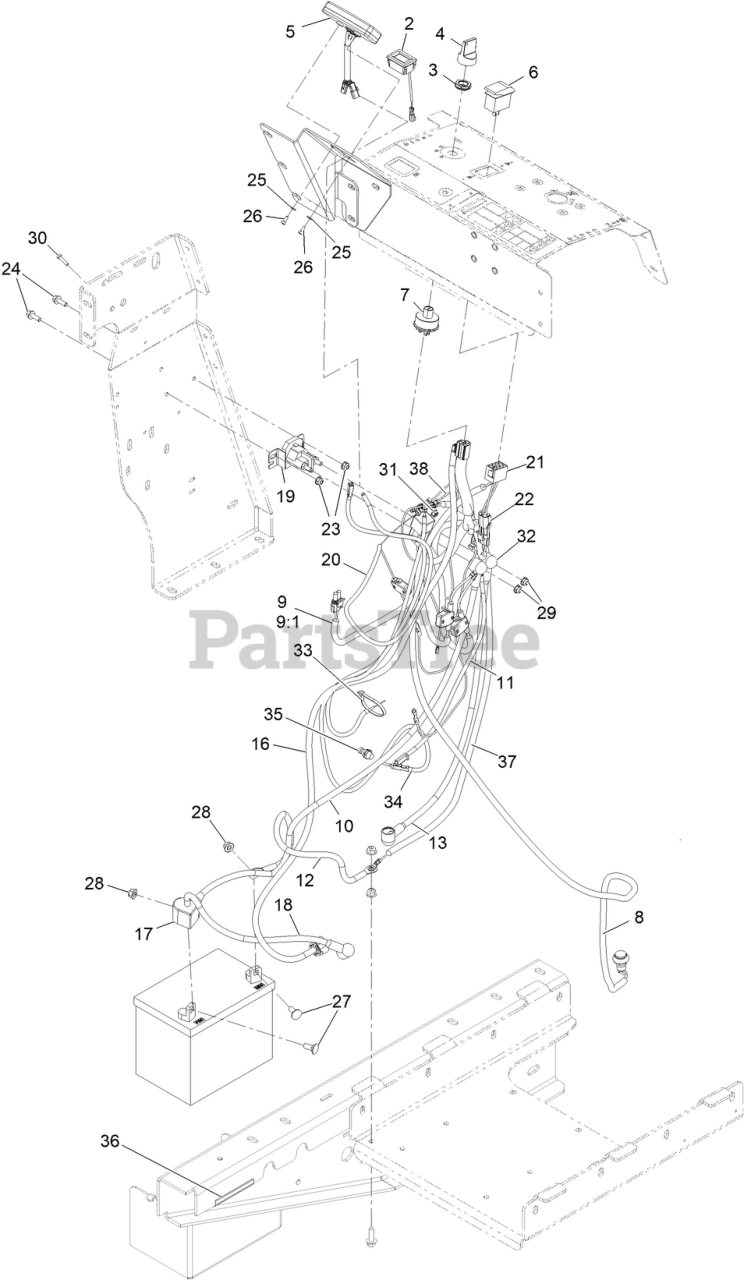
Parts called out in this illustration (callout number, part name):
2	METER-TACH/HOUR
3	NUT-SWITCH, KEY
4	KEYS-IGNITION (SPARE PAIR
4	KEY-UMBRELLA
5	HEAD ONLY, STRIKER
6	SWITCH-ROCKER
7	SWITCH-IGNITION
8	Switch-Push Button
9	Harness, Main
9:1	2010 RELAY ONLY
10	CABLE-POSITIVE
11	Wire-Solenoid
12	CABLE-GROUND
13	CABLE-POSITIVE
16	Harness, Alternator
17	Insulator-Battery
18	CABLE-POSITIVE
19	Solenoid-Starter
20	HARNESS-STRIKER
21	CONNECTOR-CARLING, 8F
22	Connector-Wp,2M
23	Nut-Hex Flange
24	Screw-HHF
25	WASHER-FLAT
26	SCREW-HSH
27	SCREW-CARR
28	Nut-Hex Flange
30	SCREW-HH
31	Nut-Hex Flange
32	INSULATOR-SOLENOID
33	TIE-CABLE
34	Cable-Trail Tech, Sensor
35	MAGNET, SPEEDOMETER
36	STRIP-TRIM, 3.5""
37	HARNESS-WIRE, JUMPER
38	WIRE-GROUND
